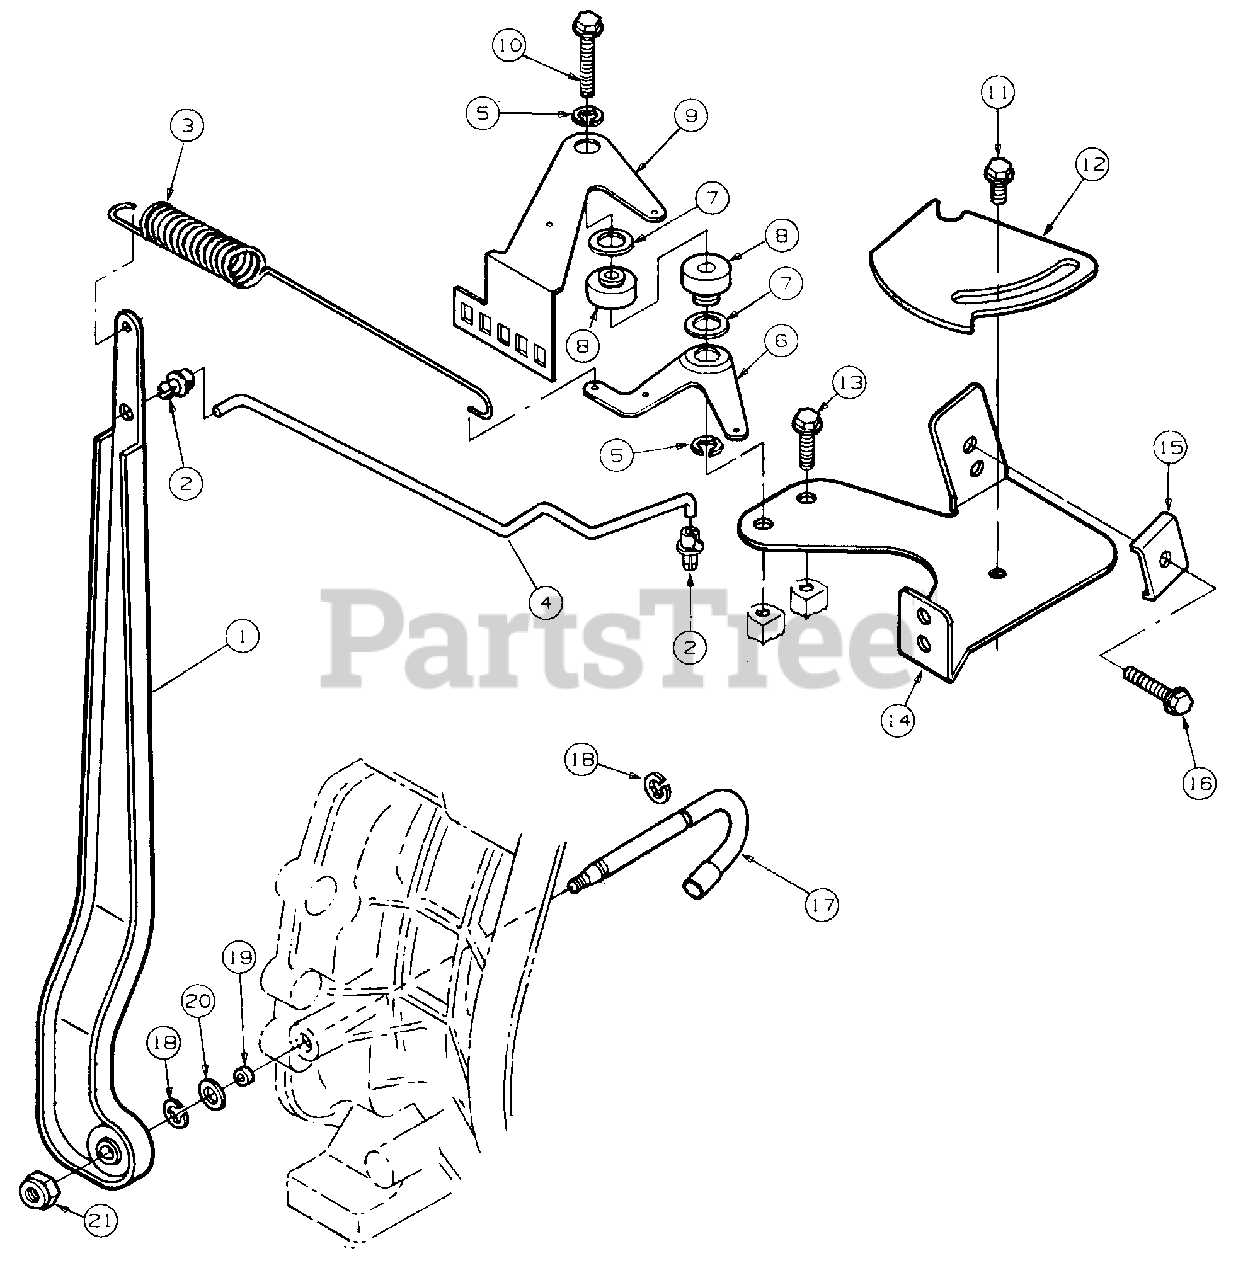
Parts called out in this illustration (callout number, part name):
1	Lever, Governor
3	Spring, Governor
4	Link, Throttle
6	Lever, Control
7	Washer, Wave Spring, M5
8	Pivot, Lever
10	Screw, Hex Flange M5 x 0.8 x 30 mm
11	Screw, Hex Flange M5 x 0.8 x 10 mm
12	Bracket, Throttle Stop
13	Screw, Hex Flange M5 x 0.8 x 16 mm
14	Bracket, Throttle Lever
16	Screw, Hex Washer Head, Thread Forming, #10-32 x 7/8
17	Shaft, Governor Lever
18	Clip, Retainer
19	Seal, Governor Shaft Lever
20	Washer, Flat, M8
21	Nut, Nylon Lock, M6 x 1
